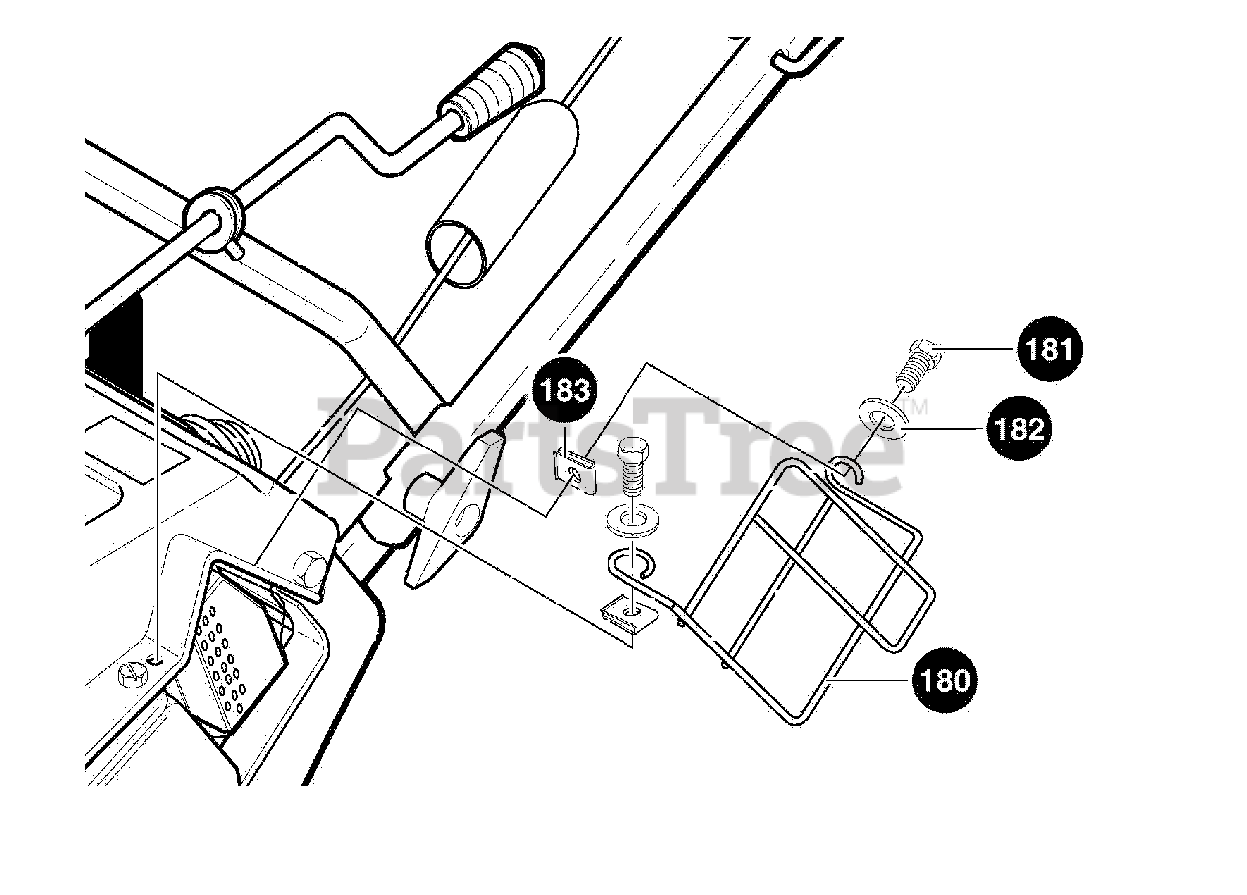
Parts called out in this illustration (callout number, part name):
180	GUARD, MUFFLER
181	SCREW
182	WASHER, FLAT
